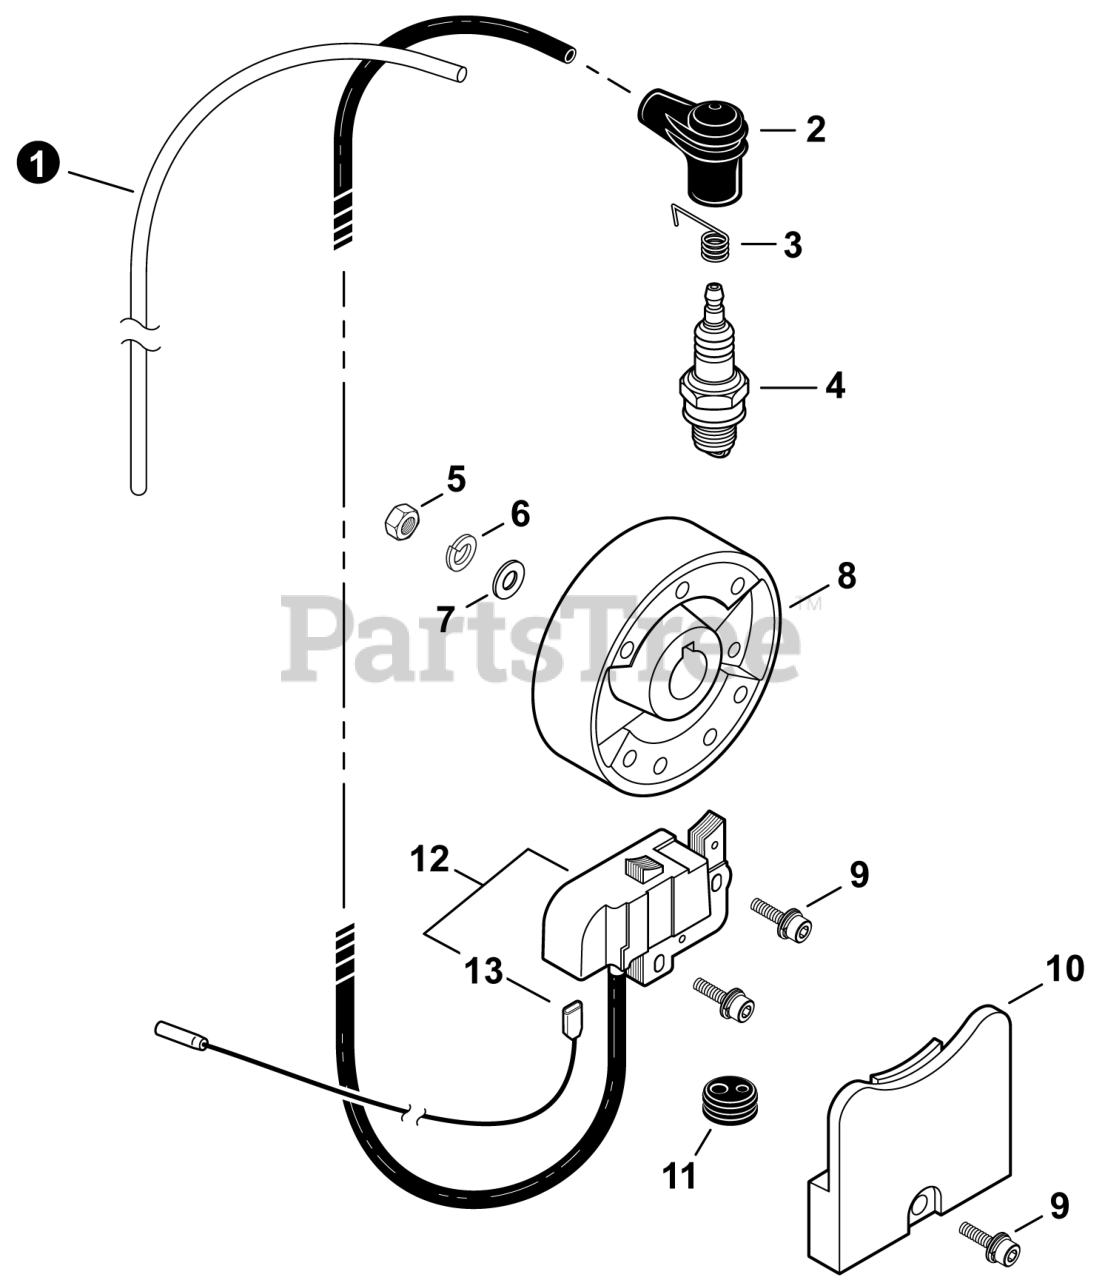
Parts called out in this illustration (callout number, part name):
1	TUBE, VINYL 6.3x8x380
2	CAP, SPARK PLUG
3	TERMINAL, SPARK PLUG
4	SPARK PLUG - BPM8Y
6	WASHER, SPRING 10
7	WASHER M10
8	FLYWHEEL
9	BOLT 5x22
10	COVER, DUST
12	COIL ASSY, IGNITION
13	LEAD - IGNITION
